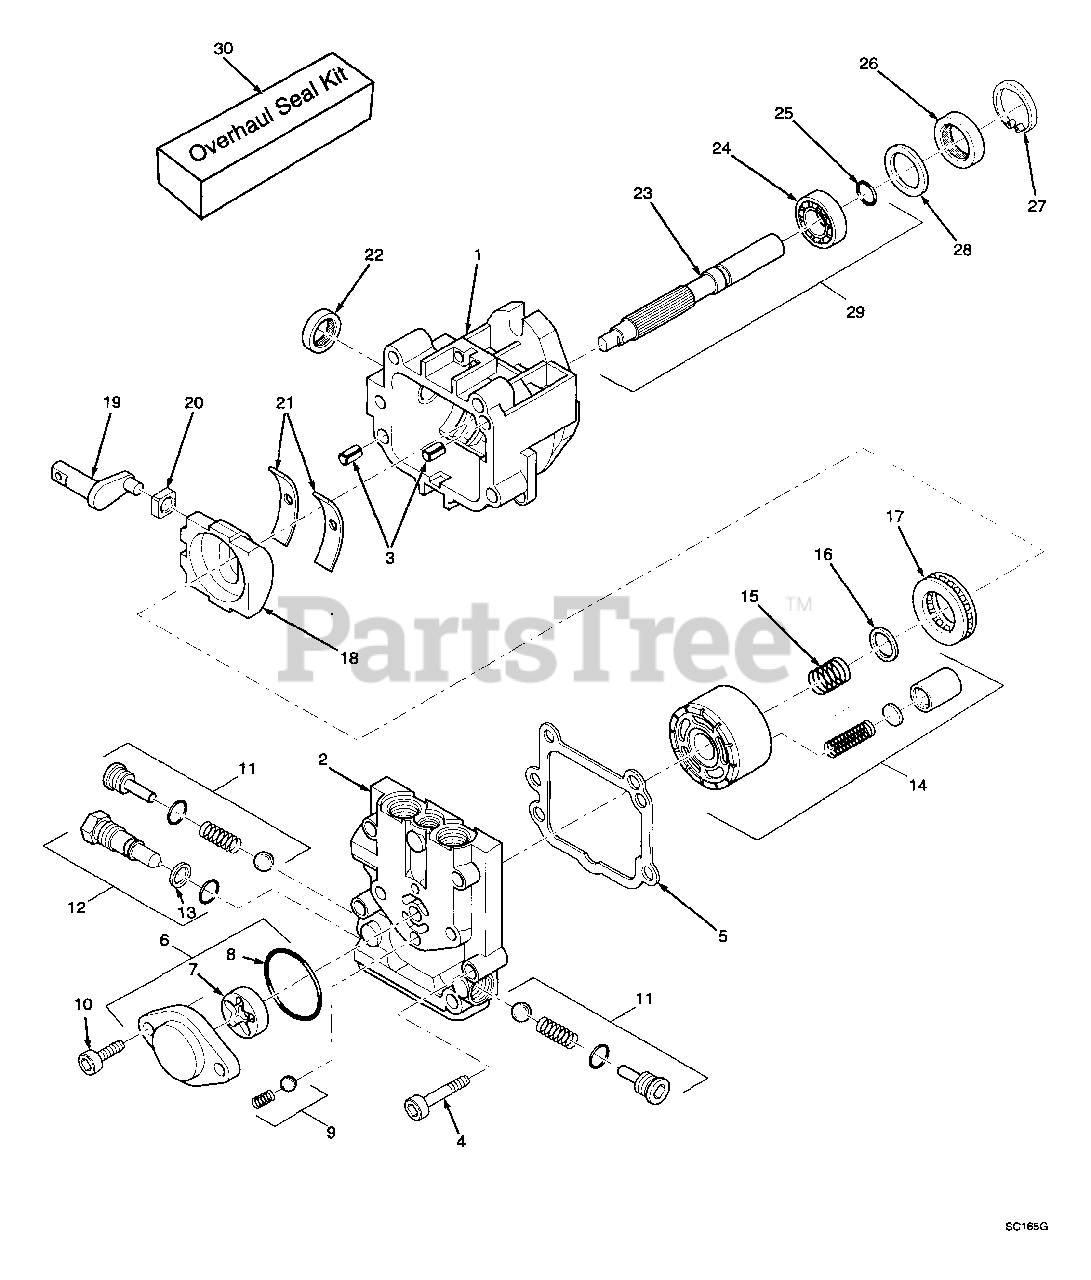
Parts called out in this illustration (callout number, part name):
1	Housing Kit
2	End Cap
3	Straight Headless Pin
4	Socket Head Screw
5	End Cap Gasket
6	Charge Pump Kit
7	Gerotor Assembly
9	Charge Relief Valve Kit
10	Socket Head Screw
11	Check Valve Kit
12	Bypass Valve Kit
13	Backup Ring
14	Cylinder Block Kit
15	Block Spring
16	Block Thrust Washer
17	Roller Thrust Bearing
18	Swash Plate
19	Trunnion Arm
20	Guide Slot
21	Cradle Bearing
23	Pump Shaft
24	Ball Bearing
25	Retaining Ring
27	Retaining Ring
29	Shaft Kit
30	Overhaul Seal Kit
